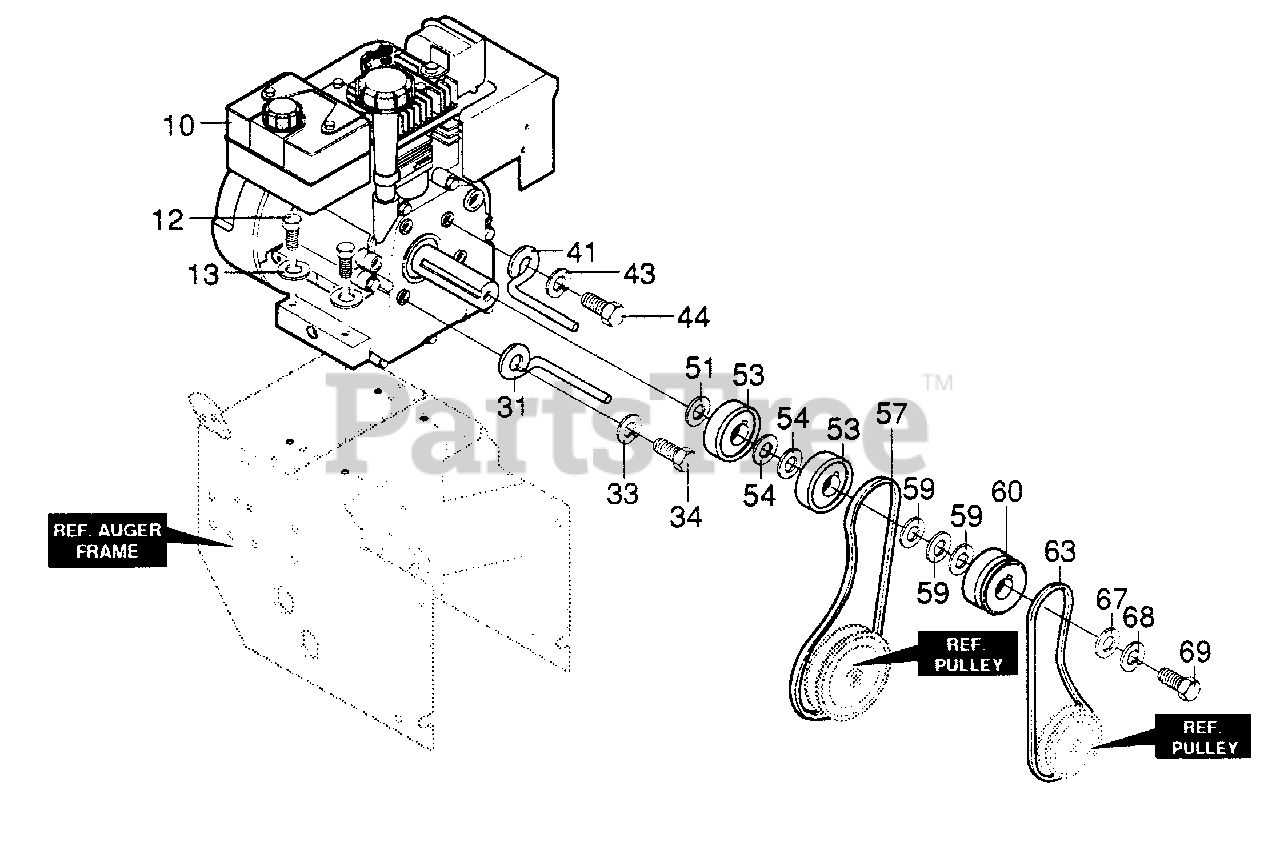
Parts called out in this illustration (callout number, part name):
10	ENGINE 8 HP TEC
12	SCREW, 5/16-180.50
13	WASHER, HVSPTLK.328x.60x.09
31	GUIDE, ROD BELT, RH
33	WASHER, HVSPTLK.328x.60x.09
34	SCREW, 5/16-24x.625 HHC
41	GUIDE, ROD BELT RH
43	WASHER, HVSPTLK.328x.60x.09
44	SCREW, 5/16-24x.625 HHC
51	WASHER, CRANKSHAFT
53	PULLEY, HALF V3L- 2.00x.752 ID
54	WASHER, FLAT .752x.91x.02
57	BELT, V 3L 33.13 LONG
59	FLATWASHER,.765x1.12x.02
60	PULLEY, ENGINE V4L
63	BELT, V 4L 38.2 LG AUG DRIVE
67	FLATWASHER .375x1.25x.104
68	WASHER, REGSPTLK.393x.68x.10
69	SCREW, 3/8-240.00 NYL
